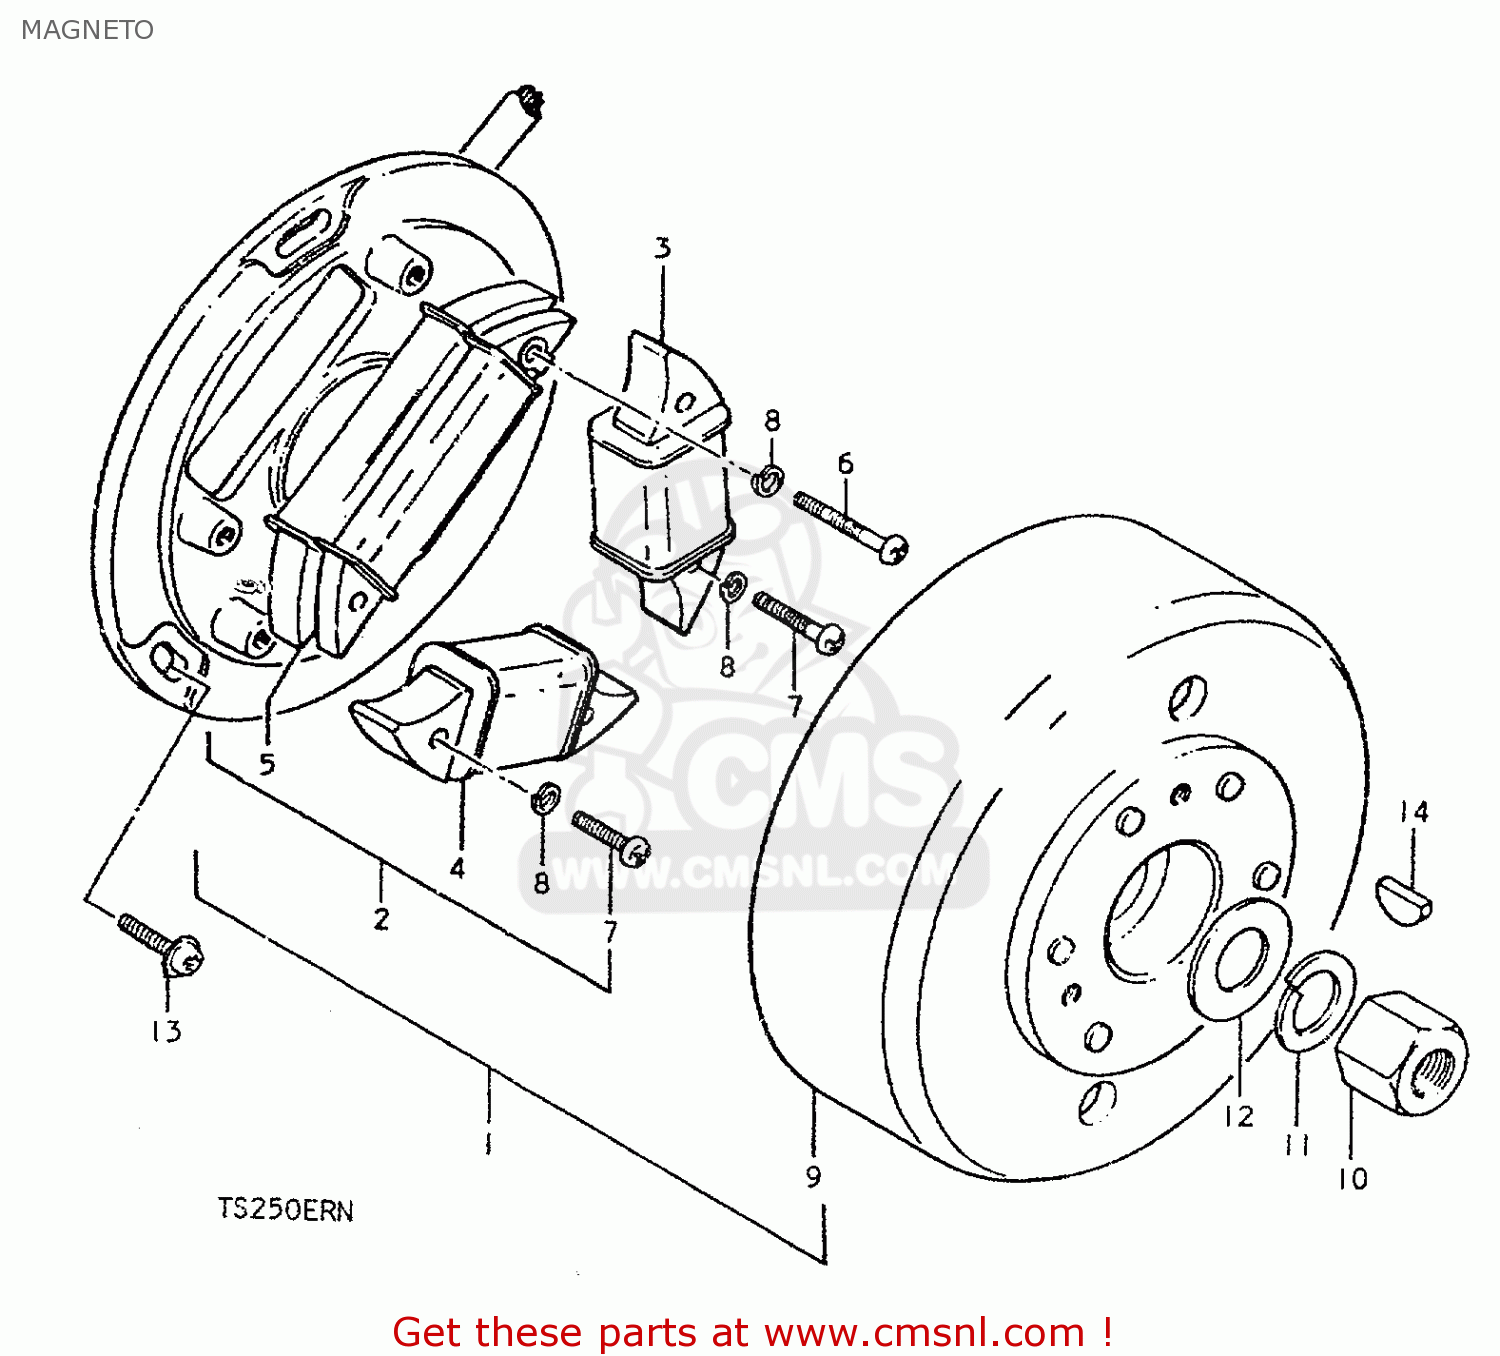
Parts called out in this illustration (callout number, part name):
1	MAGNETO ASSEMBLY
2	STATOR ASSEMBLY
3	COIL,LIGHTING
4	COIL,CHARGING
5	COIL,IGNITION
6	SCREW
7	SCREW 5X20
8	LOCK WASHER
9	ROTOR,FLYWHEEL
10	NUT
11	LOCK WASHER
12	WASHER(14X27X3)
13	SCREW(5X14)
14	KEY 4MM
